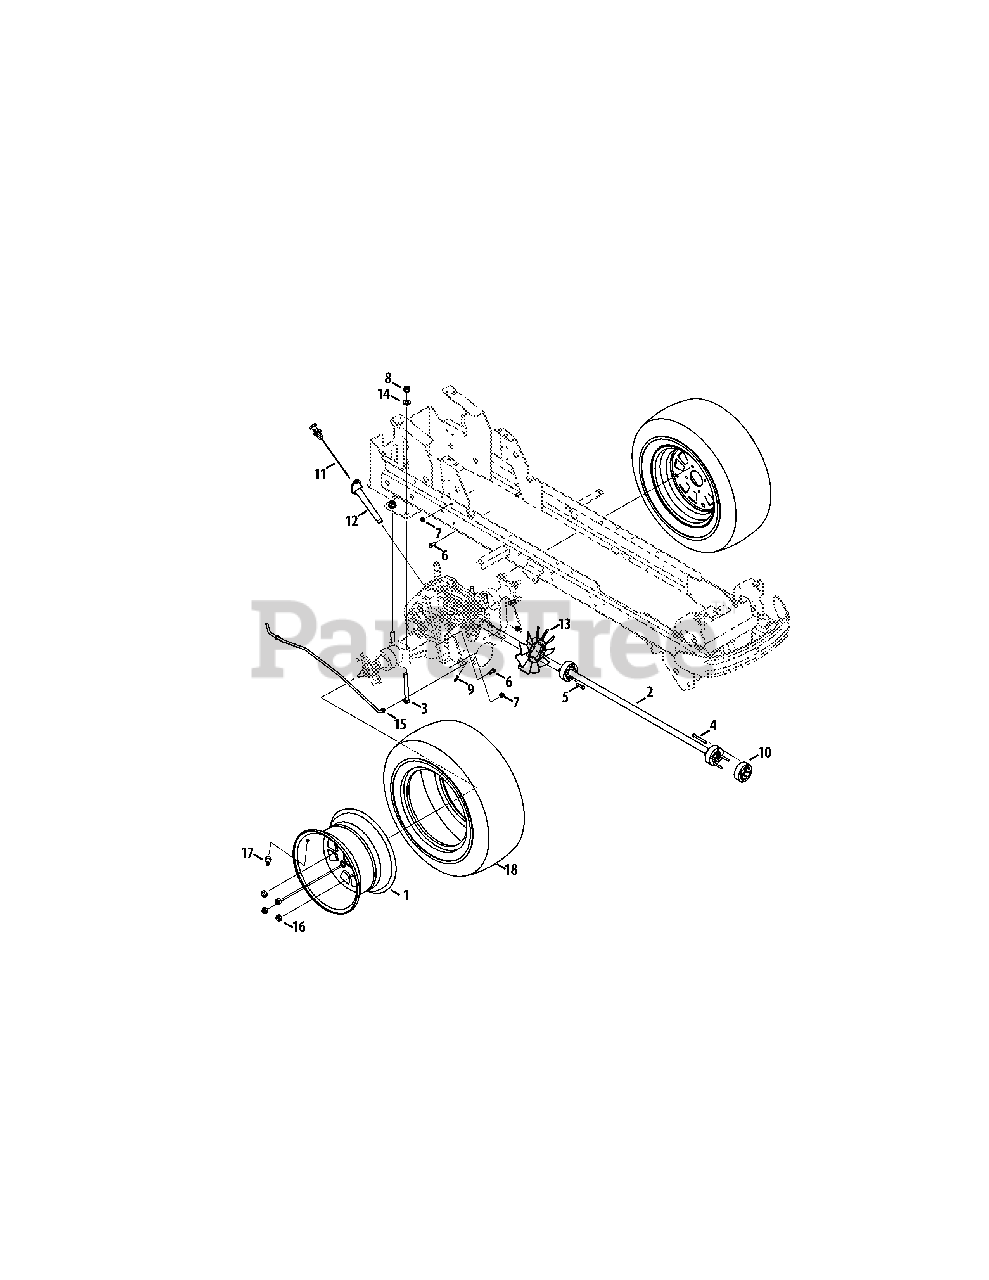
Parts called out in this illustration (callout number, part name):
1	Rim Assembly, 12.0 x 7.0
2	Shaft Assembly, 30.55
3	Hex Screw, 1/2-20 x 4.50
4	Hex Screw, 1/4-20 x 2.50
5	Hex Screw, 1/4-20 x 1.25
6	Hex Screw, 5/16-18 x .75
7	Flange Lock Nut, 5/16-18
8	Hex Lock Nut, 1/2-20
9	Bow-Tie Cotter Pin, 72
10	Drive Shaft Adapter
11	Transaxle Dipstick
12	Dipstick Holder
13	Pump Fan, 7.0
14	Flat Washer, .531 x 1.062 x .134
15	Hydro Relief Lever
16	Lug Nut, 7/16-14
17	Tubeless Air Valve
18	Tire, 23.0 x 10.5 x 12
